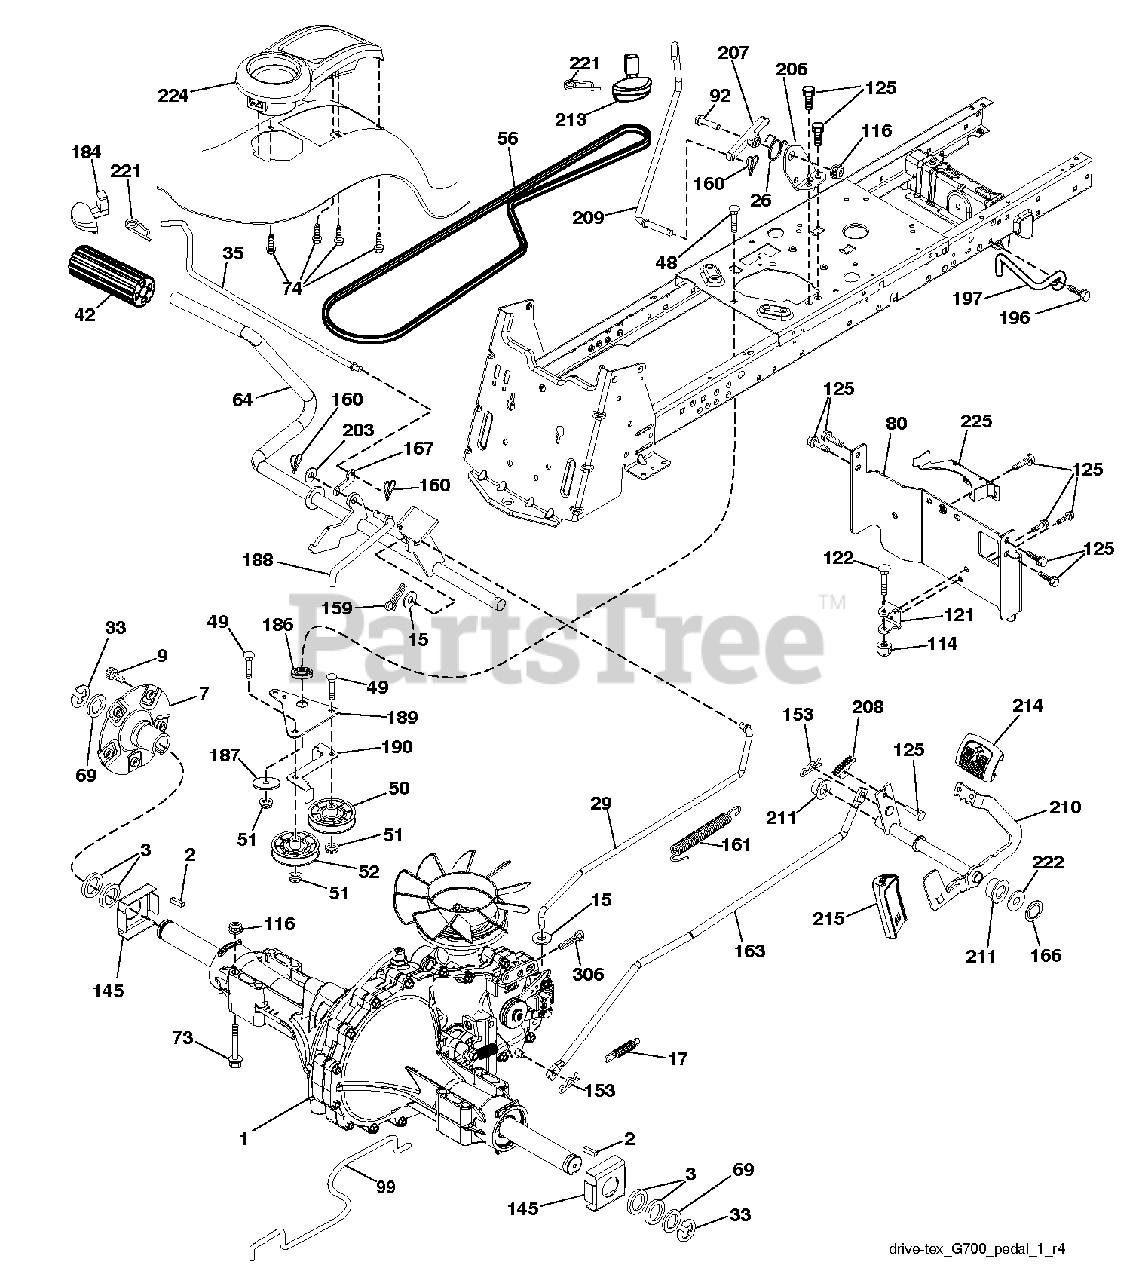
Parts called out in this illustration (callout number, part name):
3	WASHER T
7	HUB.ASM.WHEEL.REAR.23"TEX
9	HUB BOLT
15	WASHER
26	SPRING.RETURN.CRUISE
33	E RING HYT
35	ROD.BRKAE.PARKING.STEALTH
48	BOLT.3/8-16X1.50
50	IDLER.FLAT.910.OFFSET
52	IDLER.V-GROOVE.910.OFFSET
64	SHAFT.ASM.PEDAL.BRK.CNTR
73	BOLT HEX 5/16-18 GR 5
74	SCREW.HI-LO.CONSOLE
114	NUT.71038.31-18.HEX.NYLOCK
116	NUT LOCK HEX FLANGE 5/16-18
159	COTTER PIN
160	RETAINER CLIP
161	SPRING, RETURN LT
166	NUT.PUSH.625
167	LATCH.BRAKE.SPRING
186	SPACER.RETAINER
188	LINK.CLUTCH.GROUND.DRIVE
196	SCREW 3/8-16X1
197	BRKT.ANIT-ROTATION.CLU
207	LATCH.CONTROL.CRUISE
208	GEAR.SECTOR.CONTROL.CR
209	ROD.CONTROL.CRUISE.STEALTH.TEX
210	ROCKER.ASM.PEDAL.CONTR
211	BEARING.NYLON
213	KNOB.CONTROL.CRUISE
214	PAD PEDAL FORWARD
215	PEDAL.REVERSE.TEX.GT.4
221	RETAINER.SPRING.CLIP.H
222	WASHER 21/32 X 1-1/4 X 10 GA.
224	CONSOLE.TOOLBOX.PCH.ERGO.BLACK
